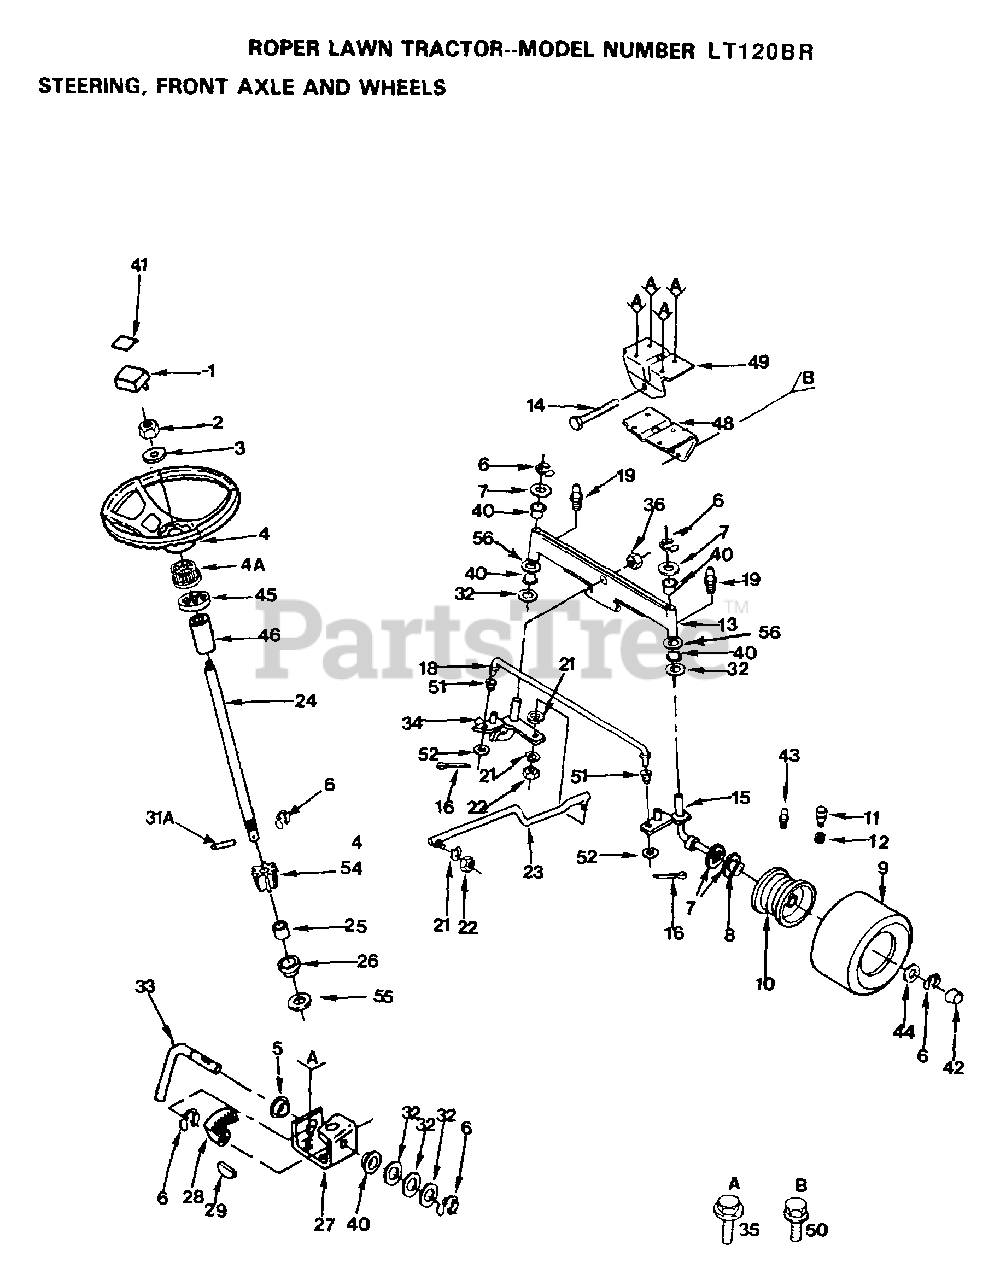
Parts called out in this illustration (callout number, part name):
1	INSERT-WHEEL LT
3	WASHER
4A	ADAPTER LT
5	NYLINER T
6	RING
8	"FLANGE, BEARING"
11	VALVE STEM LT
12	VALVE CAP
13	FRONT AXLE
14	BOLT LT
16	COTTER PIN
19	ZERK M
20	BEARING
21	LOCKWASHER
23	LINK-DRAG LT
25	SHAFT SPACER LT
26	BUSHING
28	GEAR.SECTOR.HYT
29	KEY-WOODRUFF LT
30	WASHER D
32	WASHER .T
33	ROD STEERING T
34	SPINDLE-LH LT
35	SCREW
36	"NUT-LOC,FLANGE LT"
40	COL. SRTG. BEAR.
41	DECAL - STEERING WHEEL
42	HUB CAP
43	FITTING LT
48	SUPPORT.SADDLE.FT
49	SUPPORT-SADDL T
50	SCREW LT
52	WASHER
54	GEAR PINION T
56	WASHER
